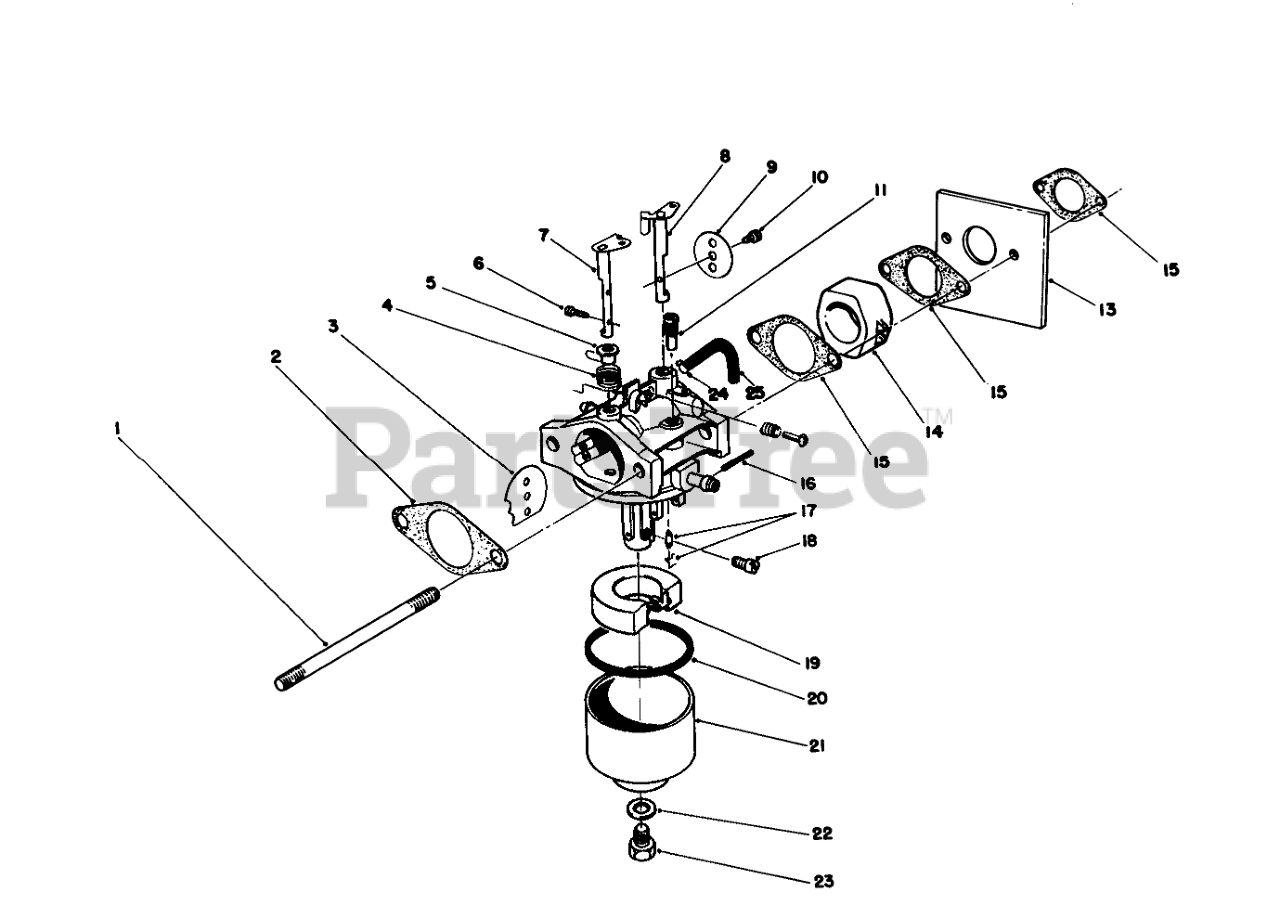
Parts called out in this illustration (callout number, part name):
1	STUD-CARBURETOR
2	GASKET-AIR CLEANER
3	PLATE
4	SPRING
5	BUSHING
6	SCREW
7	SHAFT-CHOKE
8	SHAFT
9	PLATE
10	Screw-Throttle
11	PILOT JET
13	SHIELD-CARBURETOR
14	INSULATOR-CARBURETOR
15	GASKET-CARB
16	Pin
17	NEEDLE
18	JET-MAIN
19	FLOAT
20	GASKET
21	BOWL - FLOAT
22	GASKET
23	SCREW
24	CLAMP
25	VENT TUBE
26	GASKET
